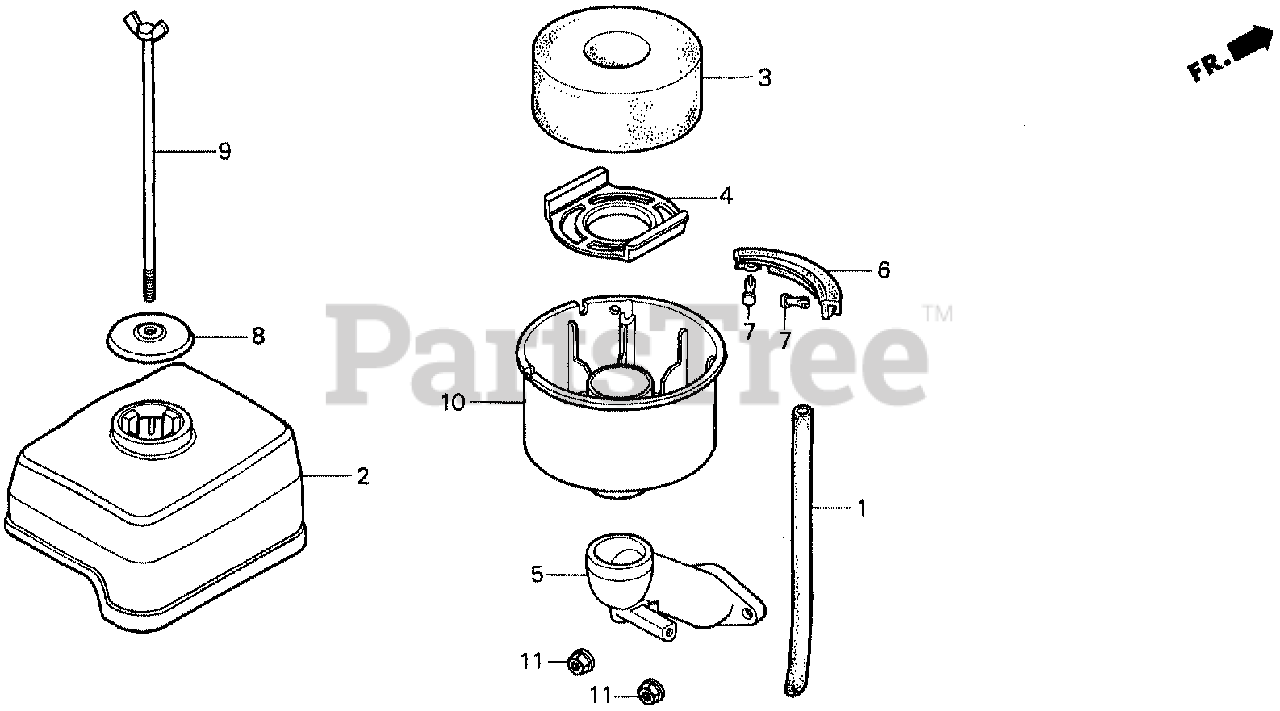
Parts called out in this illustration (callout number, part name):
1	TUBE, BREATHER
2	BODY, AIR CLEANER
3	ELEMENT, AIR CLEANER
4	GRID, AIR CLEANER
5	ELBOW, AIR CLEANER
6	GASKET, OIL CLEANER (NOT AVAILABLE)
7	RIVET, PLASTIC
8	CAP, AIR CLEANER
9	BOLT, AIR CLEANER
10	PAN, AIR CLEANER OIL
11	NUT, FLANGE (6MM)
